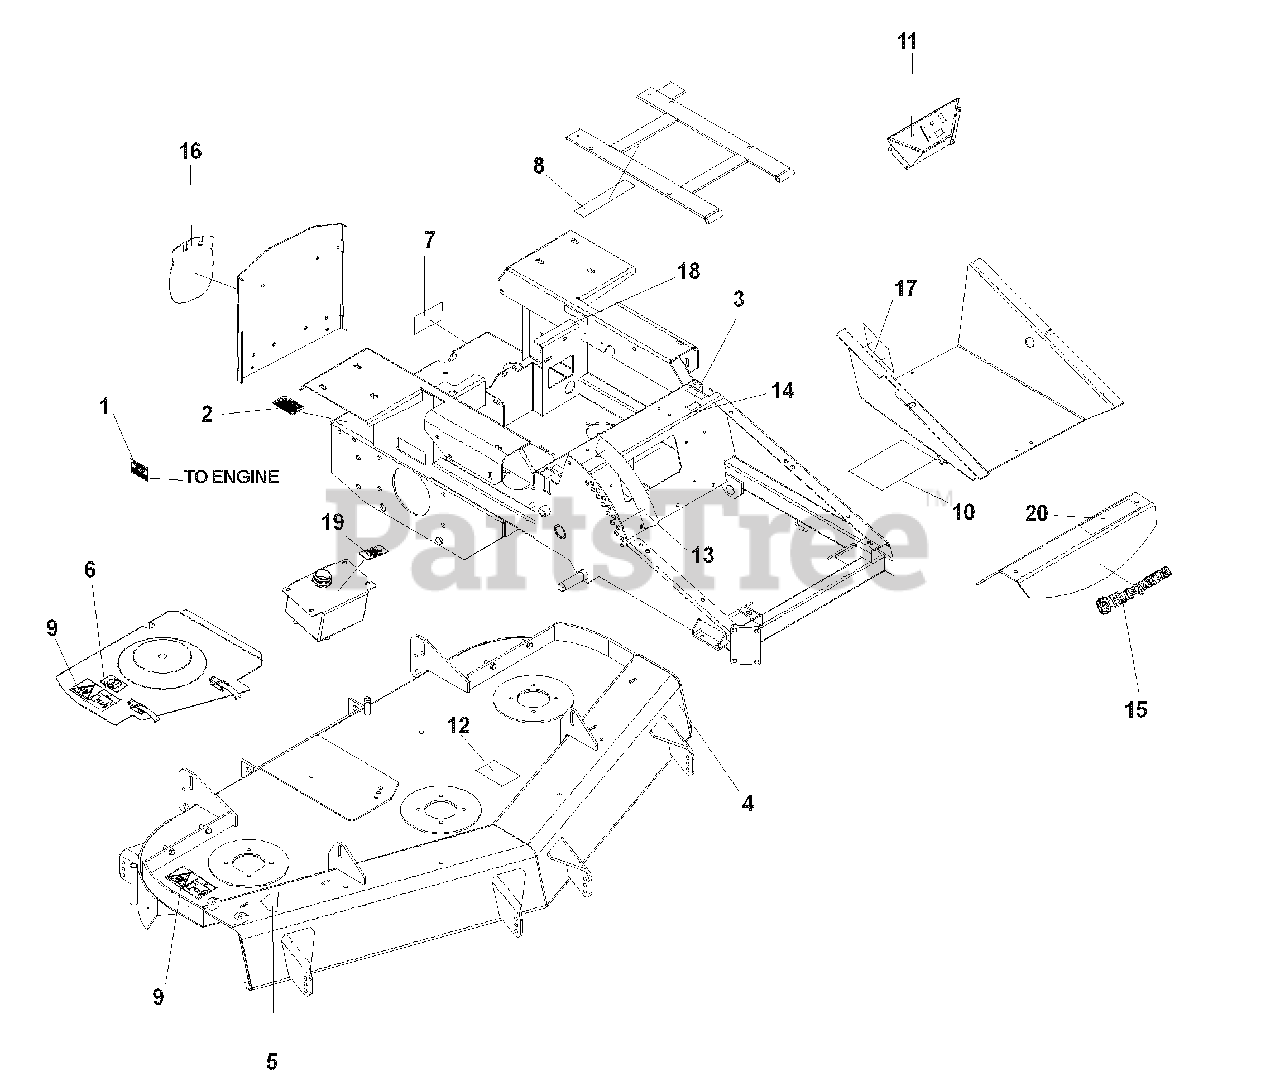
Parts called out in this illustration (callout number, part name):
1	DECAL, EXHAUST
2	DECAL, PROP 65
3	DECAL, MOTION CONTROL
4	DECAL, NASCAR
5	DECAL, WARNING
6	DECAL, EURO NO STEP
7	DECAL, EURO DANGER, BLT
8	DECAL, EURO BATT WARNG
9	DECAL, EURO SEVERING
10	DECAL, SERVICE
11	DECAL, CONSOLE
12	DECAL, BELT ROUTING
13	DECAL, HEIGHT ADJ
14	DECAL, HST
15	DECAL, HUSQVARNA
16	DECAL, CROWN
17	DECAL, WARNING
18	DECAL, RELAYS
19	DECAL, OIL TANK
20	DECAL, IZ4217
